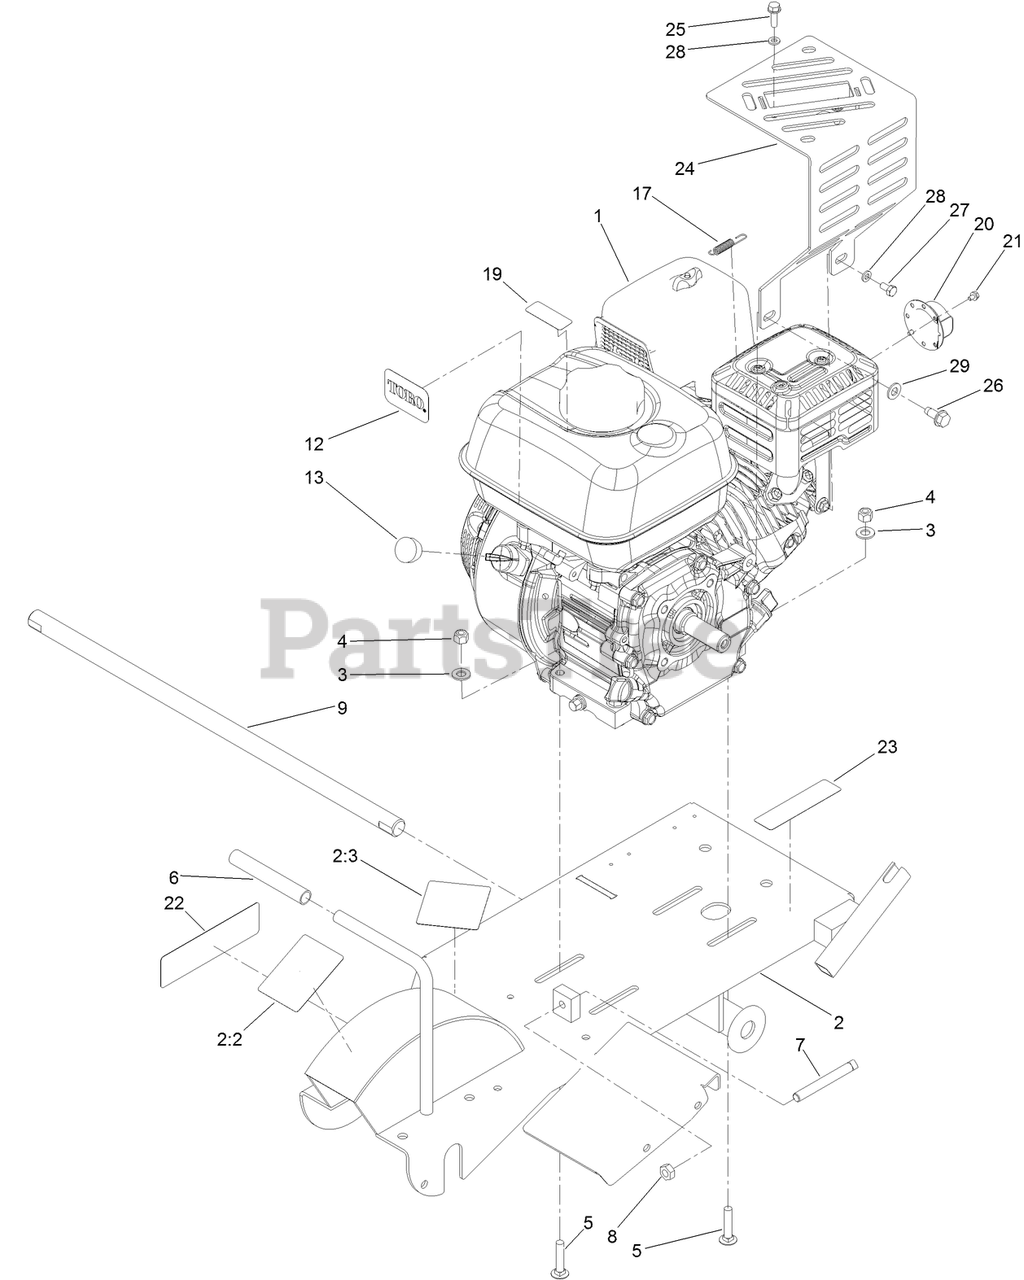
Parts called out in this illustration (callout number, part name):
2	FRAME ASM
2:2	DECAL-CAUTION
2:3	DECAL-DANGER
3	WASHER-FLAT
4	NUT-LOCK, NI
5	BOLT-CARR
6	GRIP-RUBBER
7	SCREW-SET, SQH
8	NUT-HEX
9	BAR-AXLE, WHEEL
12	DECAL
13	PLUG-ENGINE
17	SPRING-EXTENSION
19	DECAL-WARNING, ETHANOL
20	DEFLECTOR
21	SCREW-HWH
22	DECAL-ROTATE TOOTH
23	DECAL-ARRESTER, SPARK
24	GUARD-MUFFLER
26	SCREW-HWHTF
27	SCREW-HH
28	WASHER-FLAT
29	WASHER-PLAIN
